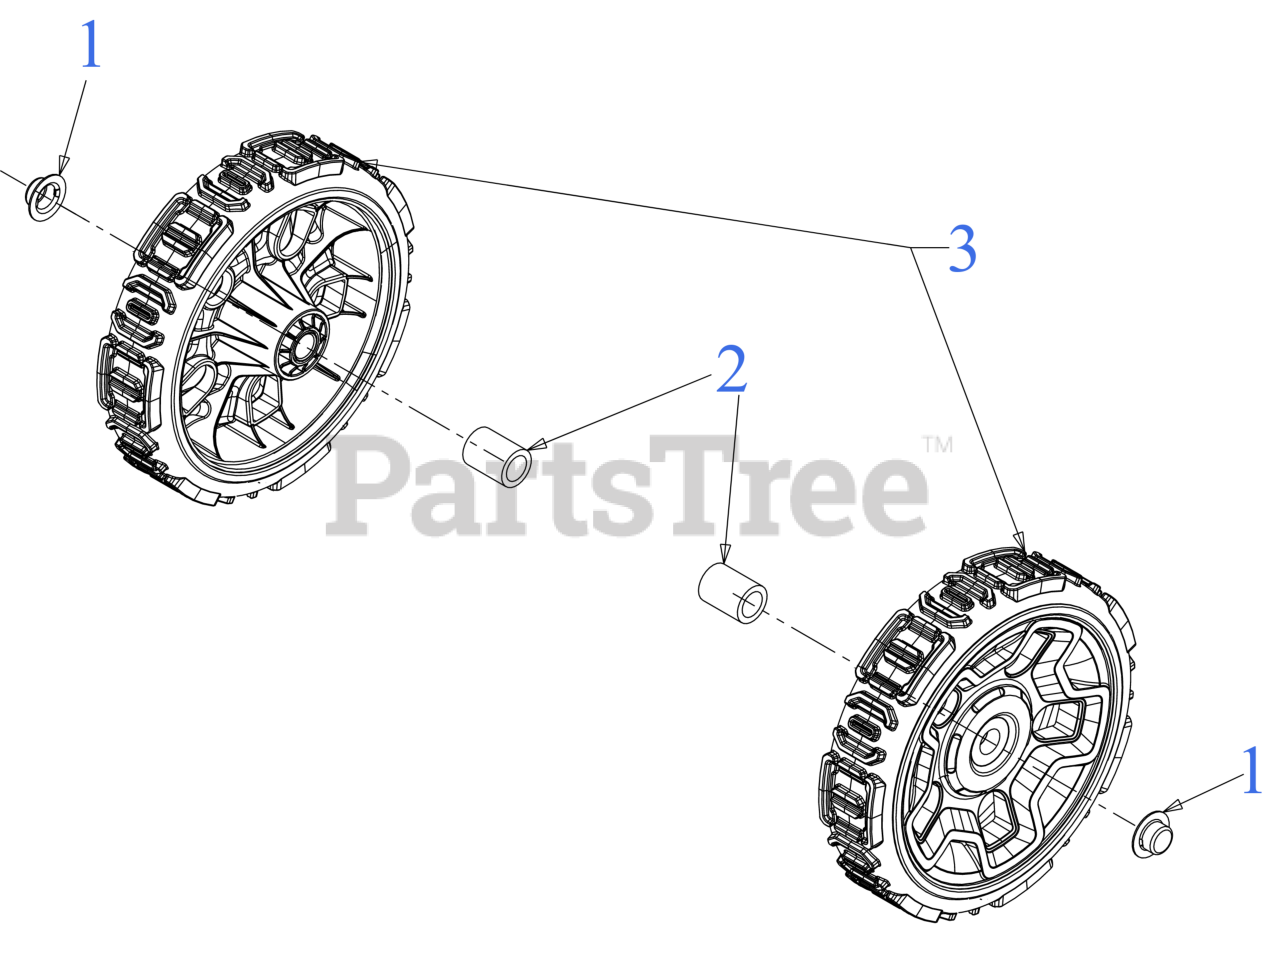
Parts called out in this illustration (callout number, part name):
1	PUSH CAP
2	SPACER .525 x .775 x 1.015
3	WHEEL-7X1.5
